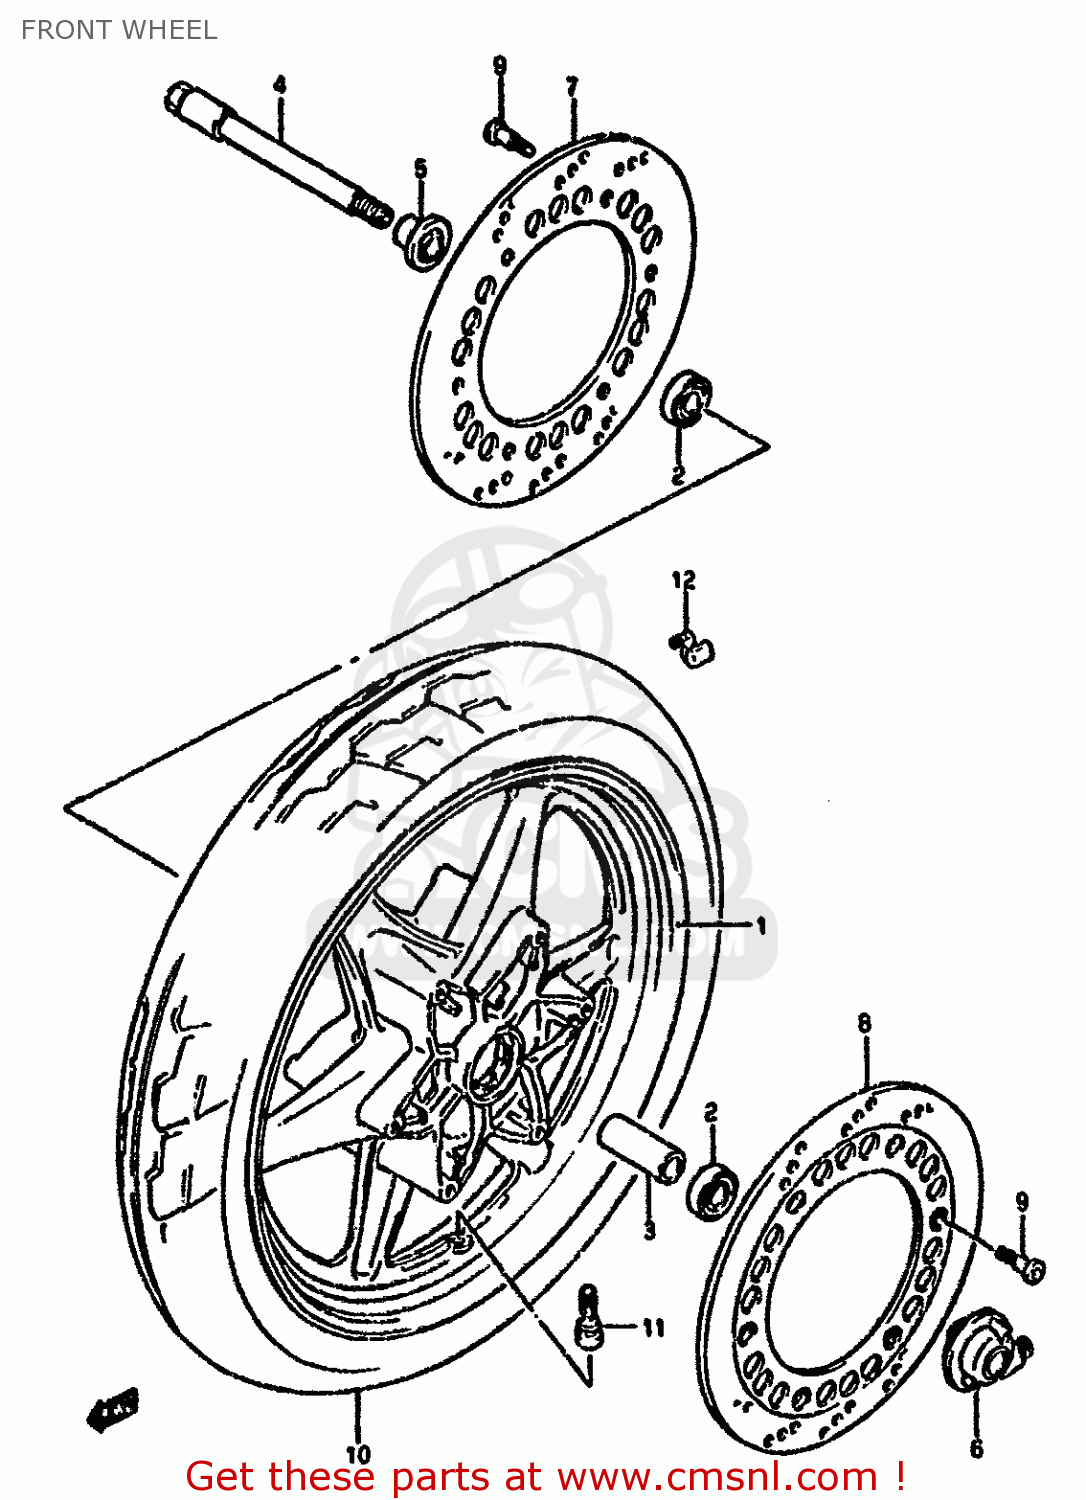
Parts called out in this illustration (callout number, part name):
1	WHEEL,FRONT
2	BEARING
3	SPACER(17.5X25X70)
4	AXLE,FR
5	SPACER COMP,FRONT AXLE
6	BOX ASSY,SPEEDOMETER GEAR
7	DISC,FR BRAKE,R
8	DISC,FR BRAKE,L
9	BOLT 8X33
10	TIRE,FRONT (110/80 V18 V240) (METZELER)
11	VALVE ASSEMBLY,WHEEL,TR412
12	BALANCER,WHEEL
